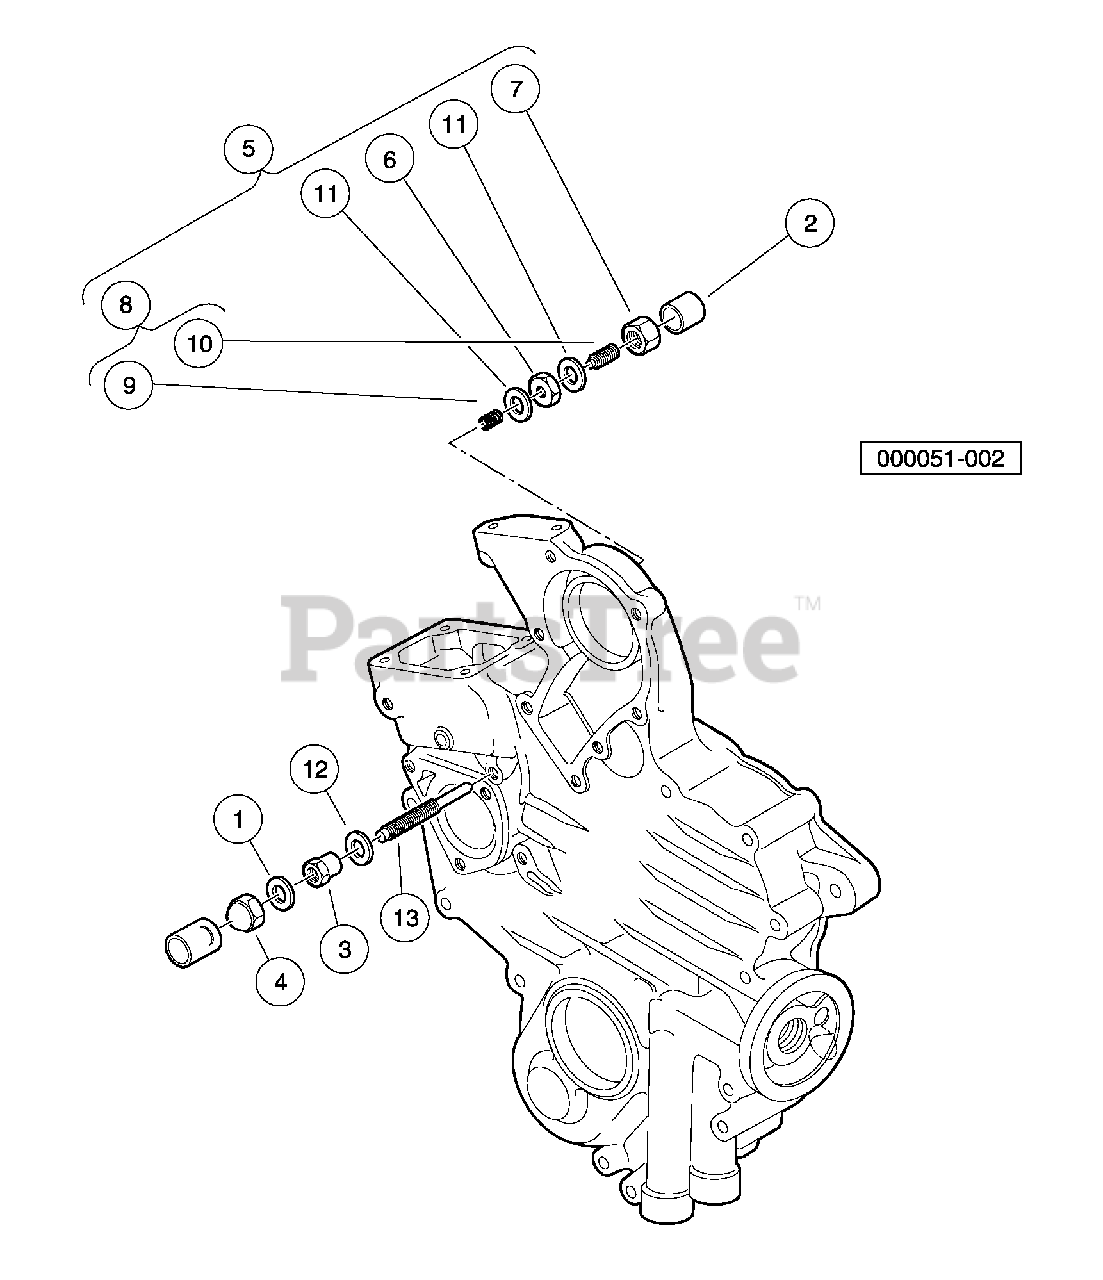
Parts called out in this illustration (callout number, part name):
1	Gasket, 6 X 10
2	Cap, Bolt Assy
3	Nut, Lock, Special
4	Nut, Special
5	Assy, Idle Apparatus
6	Nut, M8, D722 Idle App, Specl
7	Nut, M8, D722 Idle App
8	Assy, Bolt, Adjusting
9	Spring, Idle Apparatus
10	Stud, Idle Adjustment
11	Gasket, Idle Apparatus, Rear
12	Gasket, Idle Apparatus, Front
13	Bolt, Idle Adjusting.
